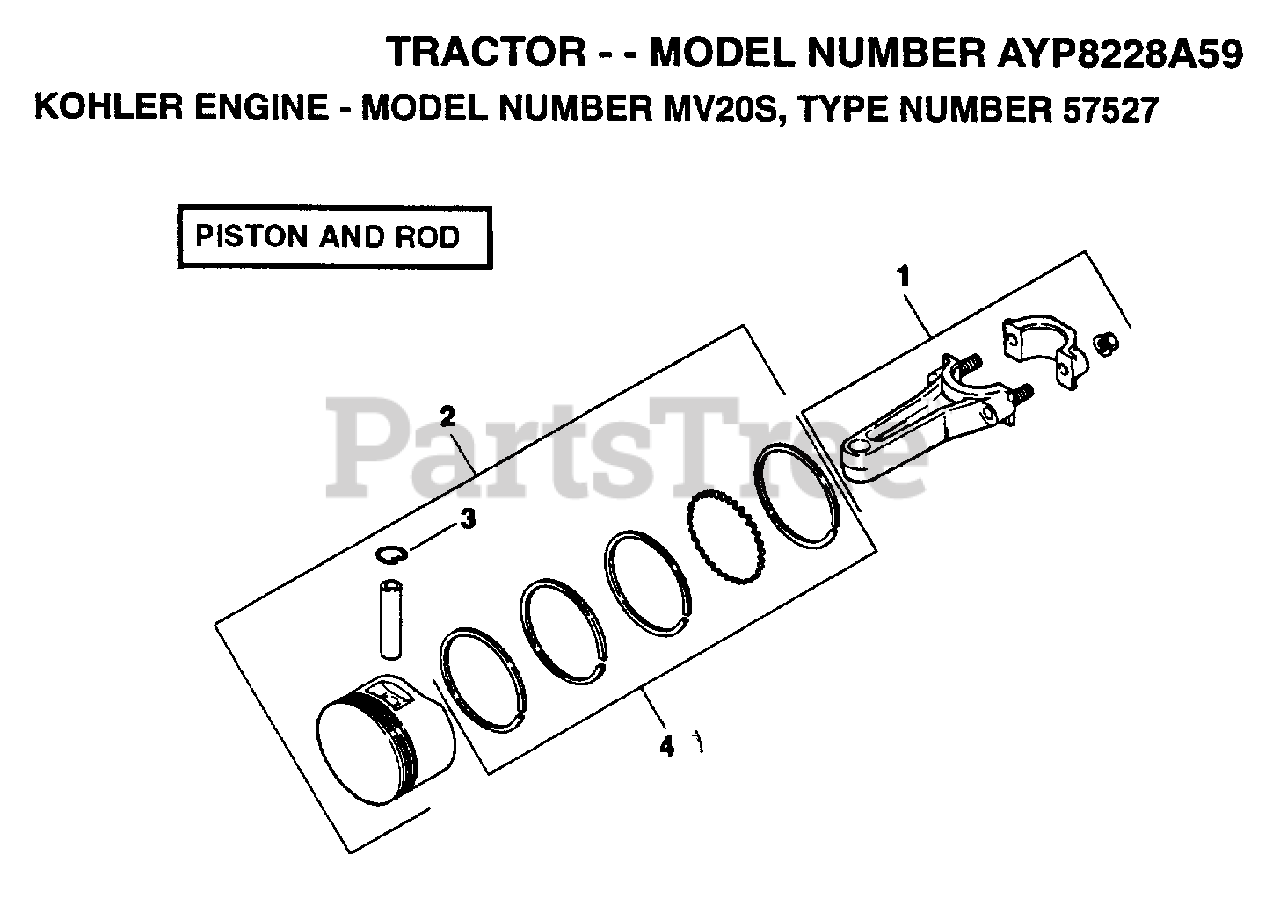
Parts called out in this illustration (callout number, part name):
1	CONNECTING ROD, STANDARD
2	PISTON WITH RING SET, STANDARD
3	RETAINER, PISTON PIN
4	RING SET, .003"
